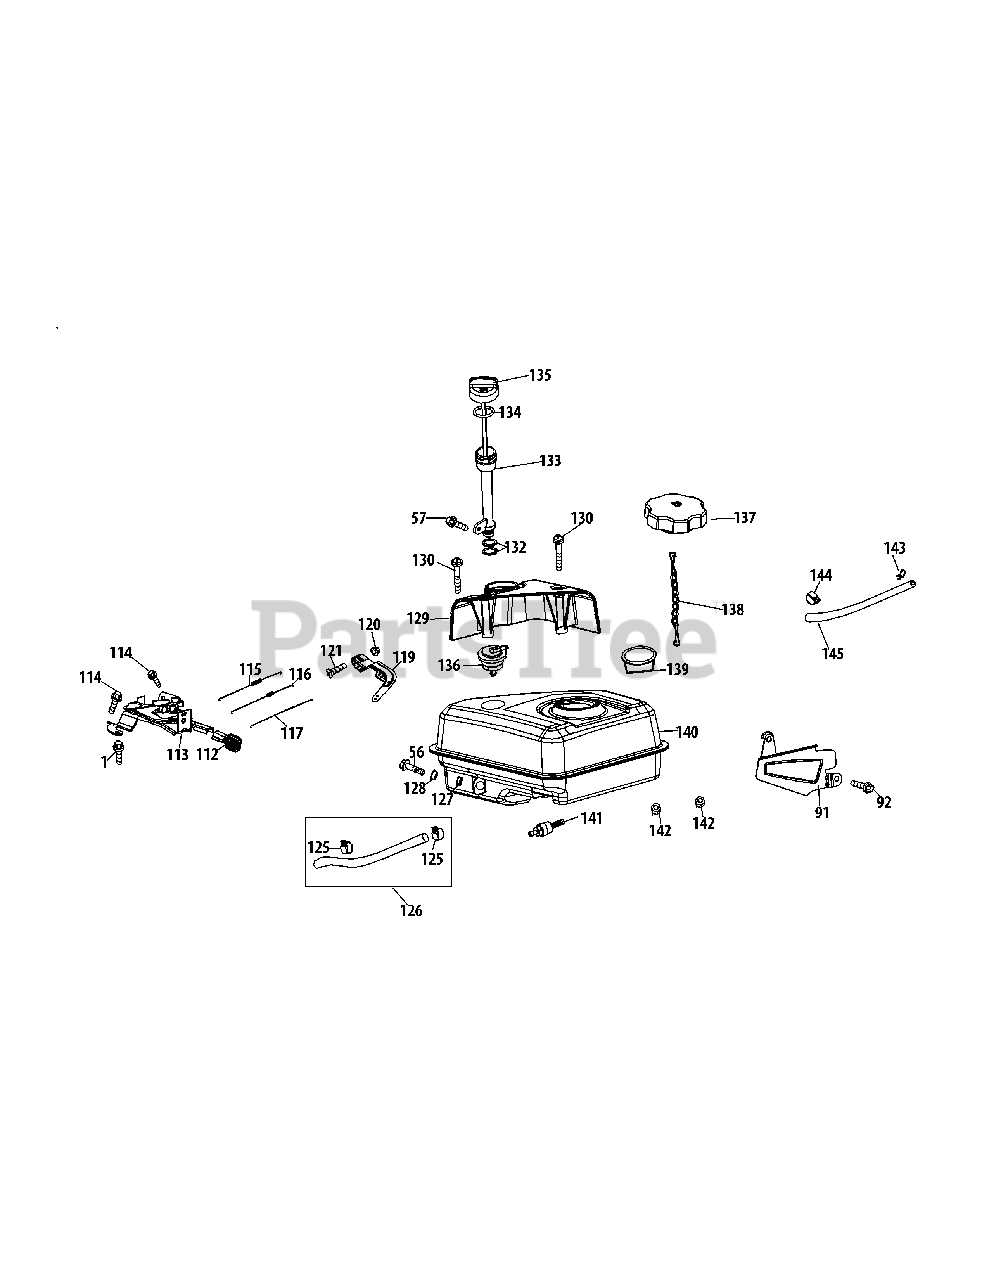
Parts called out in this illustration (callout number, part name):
1	Bolt M6×16
56	Bolt M6×12
57	Air Shield
91	Air Flow Shield
92	Bolt M6×10
112	Throttle Control Knob
113	Primer Bracket
114	Bolt M6×12
115	Governor Spring
116	Throttle Linkage Spring
117	Throttle Linkage
119	Governor Arm
120	Nut M6
121	Governor Arm Bolt
125	Fuel Hose Clamp
126	Kit-Fuel Line
127	Rubber Shock Pad
129	Dipstick Decoration Cover
132	Oil Fill Tube O-Ring
133	Oil Fill Tube Assey (Incl.132,133)
134	Oil Fill Tube O-Ring
135	Dipstick Assy - (Incl.134,135)
136	Roll Over Valve
137	Cap Comp,Fuel Feller
138	Fuel Cap Chain
139	Fuel Filter
141	Fuel Tank Nipple
143	Exhaust Piping
144	Hose Clamp
145	Primer Hose Assembly
